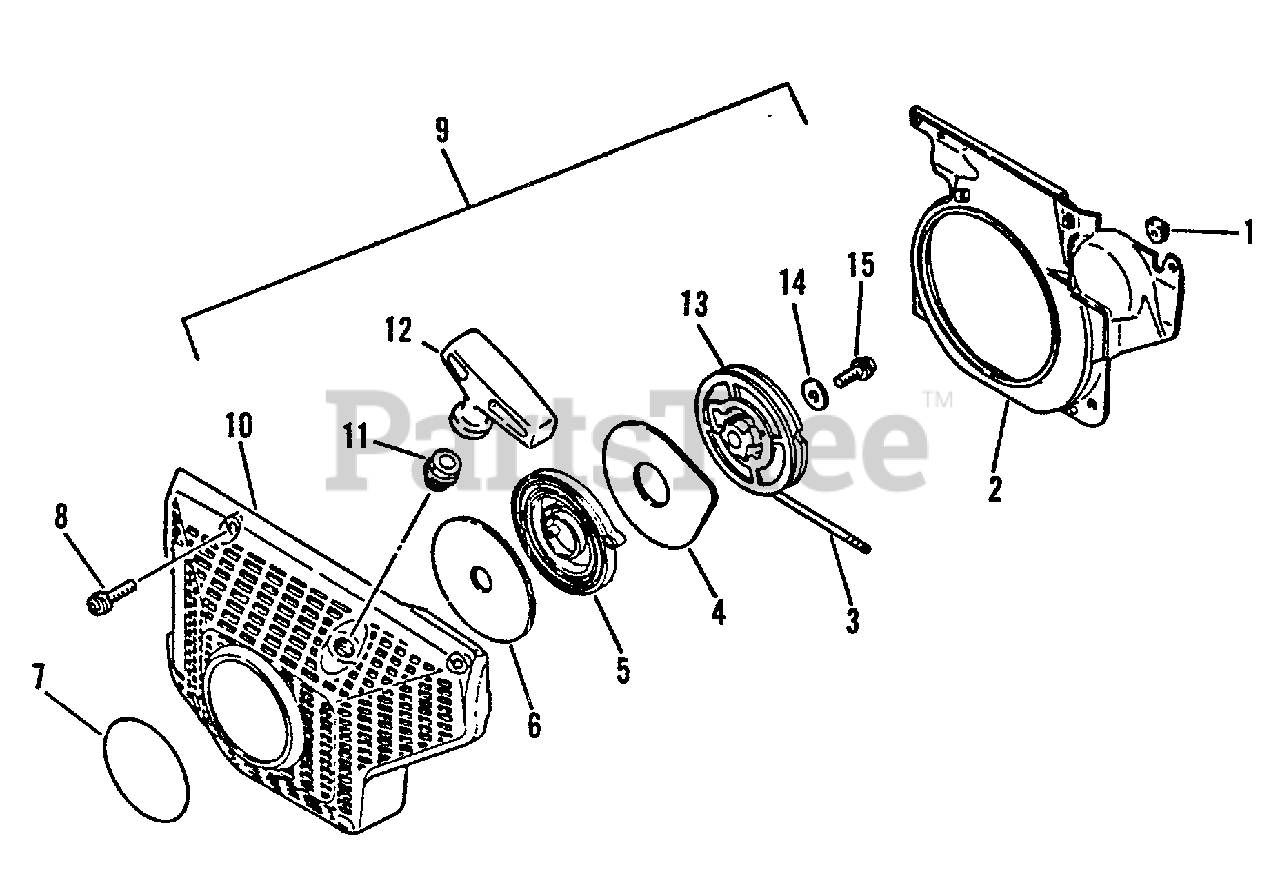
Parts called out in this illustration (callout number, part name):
2	SHIELD, FAN
3	ROPE, STARTER
4	PLATE, SIDE
5	SPRING, RECOIL
6	PLATE, SIDE
7	LABEL, ECHO
8	SCREW 5×20
9	STARTER ASSY
10	CASE, STARTER
11	GUIDE, ROPE
12	GRIP, STARTER
13	REEL, ROPE
14	WASHER 5.5×12×0.8
15	SCREW 5×14
